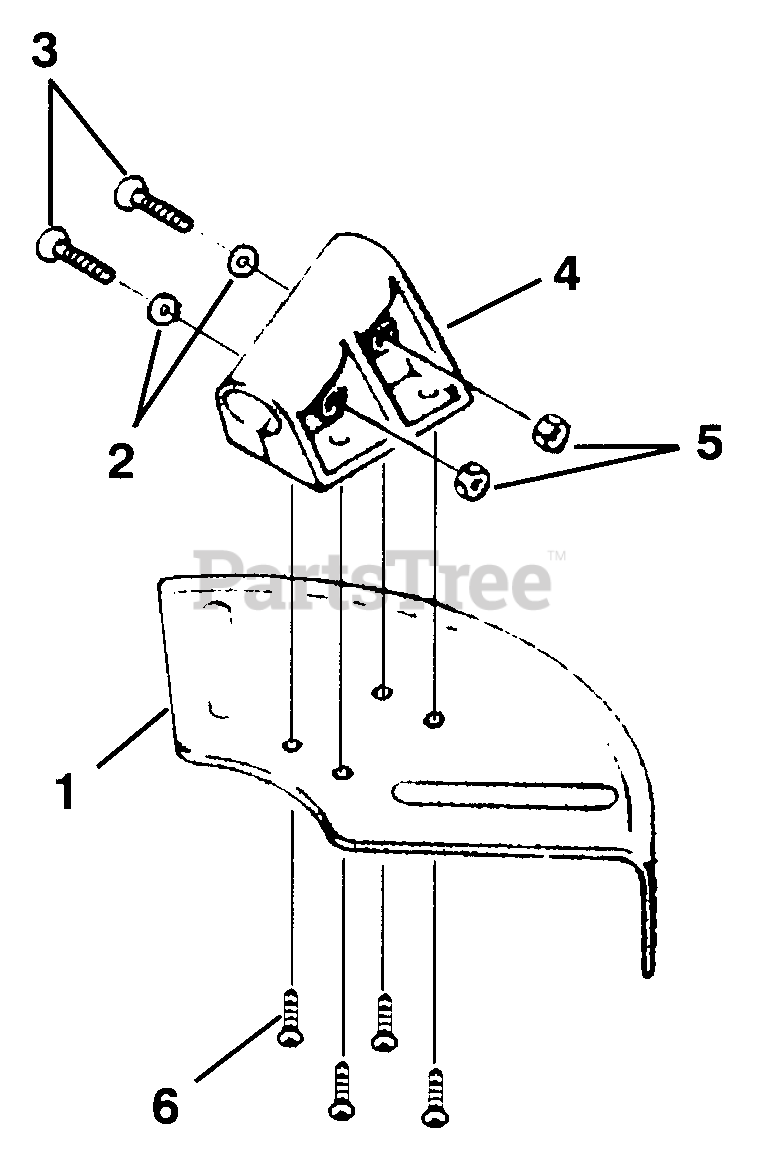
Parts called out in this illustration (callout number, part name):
1	BLADE GUARD
3	SCREW
4	BRACKET, GUARD
6	SCREW, SELF TAPPING
